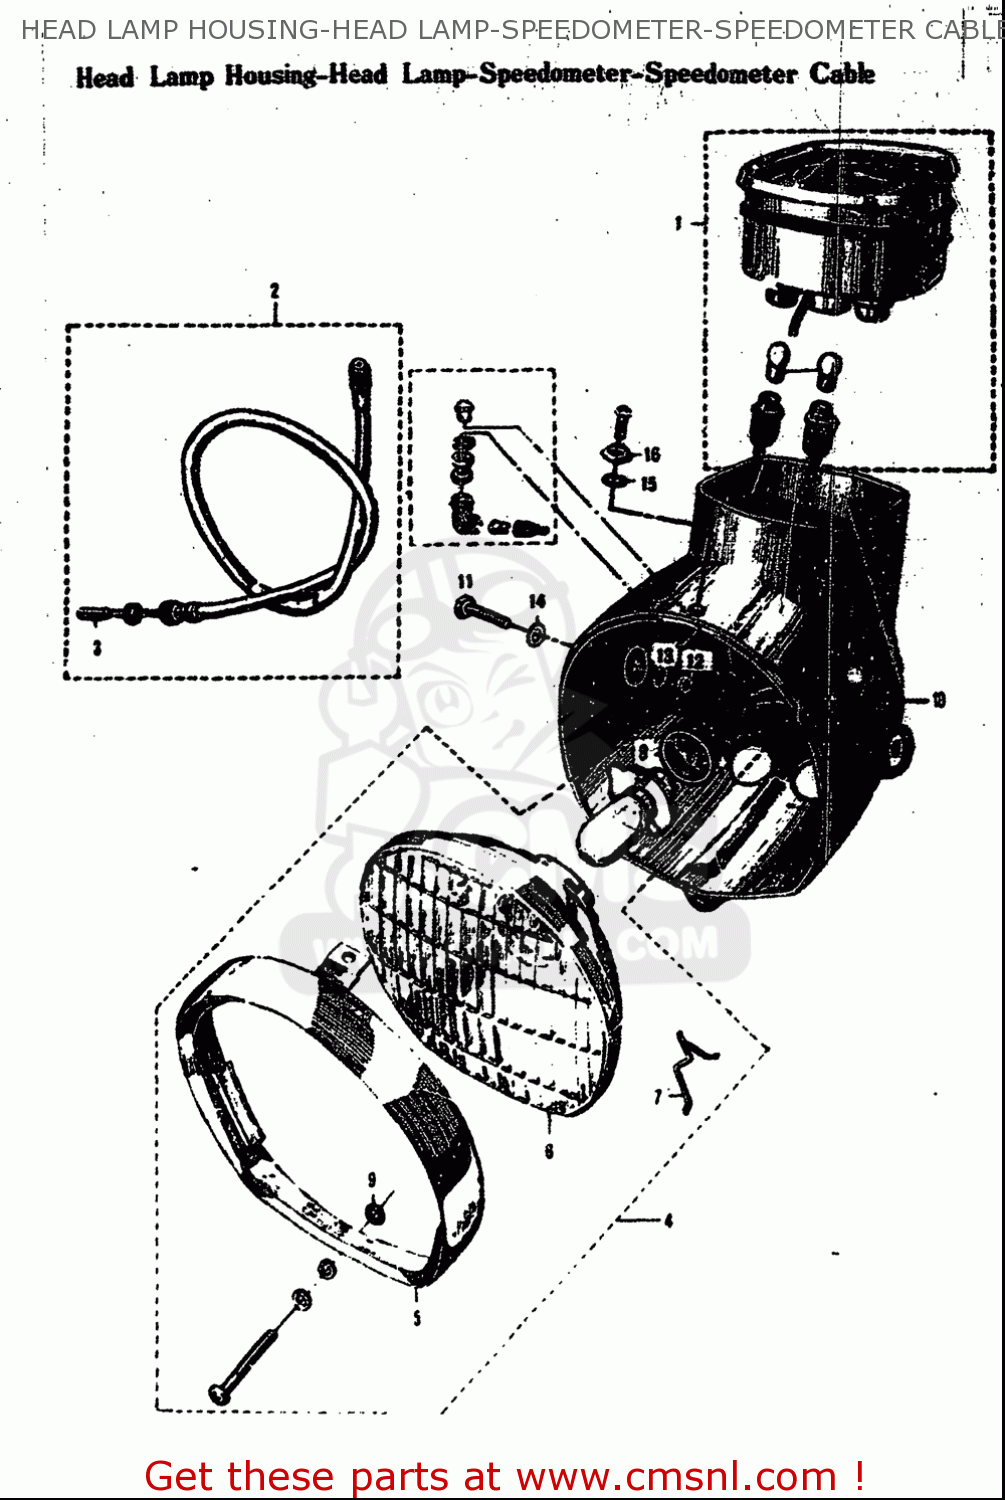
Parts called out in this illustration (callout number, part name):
11	BOLT
12	NUT
13	WASHER,LOCK
14	WASHER
15	WASHER(4X12.5X0.3)
16	WASHER
